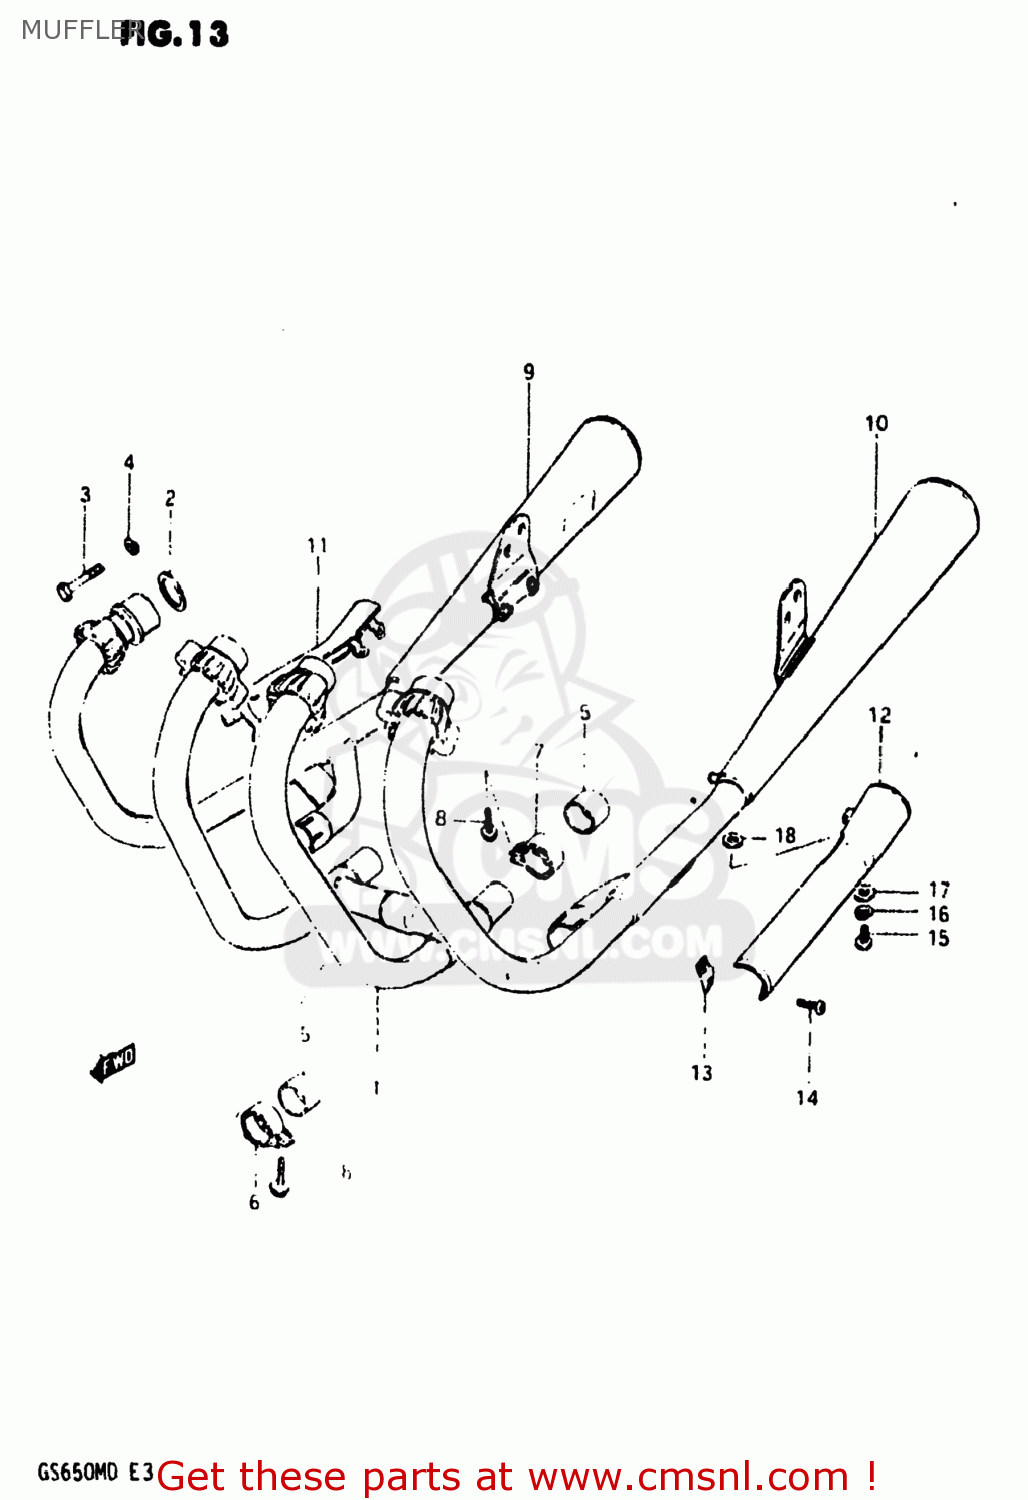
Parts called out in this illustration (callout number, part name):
1	PIPE,EXHAUST,CENTER
2	GASKET,EXHAUST PIPE (NAS)
3	BOLT 8X40
4	LOCK WASHER
5	CONNECTOR,MUFFLER
6	CLAMP,MUFFLER CONNECTOR
7	CLAMP,MUFFLER CONNECTOR
8	BOLT
9	MUFFLER ASSEMBLY
10	MUFFLER ASSEMBLY
11	COVER,MUFFLER
12	COVER,MUFFLER
13	CLAMP,MUFFLER COVER
14	SCREW 5X20
15	SCREW 6X12
16	LOCK WASHER
17	WASHER
18	GASKET 6.2X12X1.5 (MCA)
